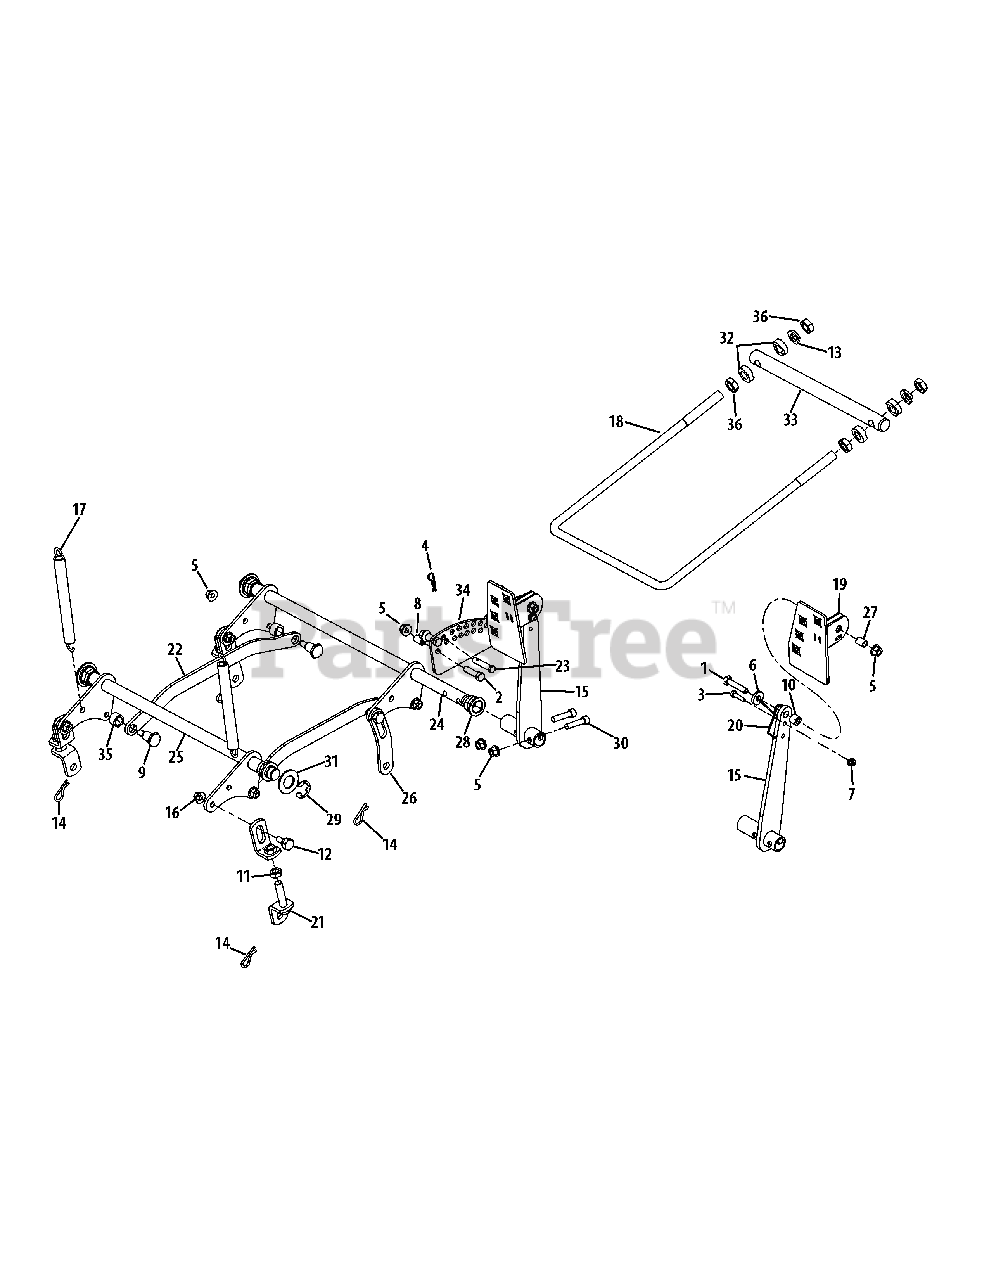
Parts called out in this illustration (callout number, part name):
1	Hex Screw, 3/8-16 x 1.75
2	Hex Screw, 3/8-16 x 1.50
3	Hex Screw, 1/4-20 x 1.00
4	Hair Pin, 3/8 x 1.562 x .080
5	Flange Counter Lock Nut, 3/8-16
6	Washer, .390 x 1.00 x .180
7	Flange Top Lock Nut, 1/4-20
8	Spacer, .375 x .500 x .750
9	Shoulder Bolt, 3/8-16 x .625 x .830
10	Spacer, .385 x .625 x .500
11	Jam Nut, 1/2-20
12	Shoulder Bolt, 3/8-16 x .56 x .27
13	Lock Washer, .633 x 1.07 x .161
14	Hair Pin, 1/2 x 1.625 x .125
16	Adjustable Deck Lift Bracket
17	Extension Spring, .75 x 7.89 x .14
18	Front Lift Rod
19	Foot Pedal Assembly
20	Torsion Spring, .900 x 2.3 x .09
21	Lower Bracket Assembly
22	Lift Connecting Link
23	Clevis Pin, 3/8 x 2.05
24	Front Shaft Assembly
25	Rear Shaft Assembly
26	Curved Link Plate
27	Spacer, .380 x .500 x .667
28	Hex Flange Bearing, 7/8
29	Retaining Clip, .675
30	Socket Cap Screw, 3/8-16 x 1.50
31	Washer, .940 x 1.75 x .110
32	Spacer, .635 x 1.2 x .41
33	Trailing Link Pivot Rod
34	Index Plate
35	Spacer, 632 x .877 x .548
36	Jam Nut, 5/8-11
